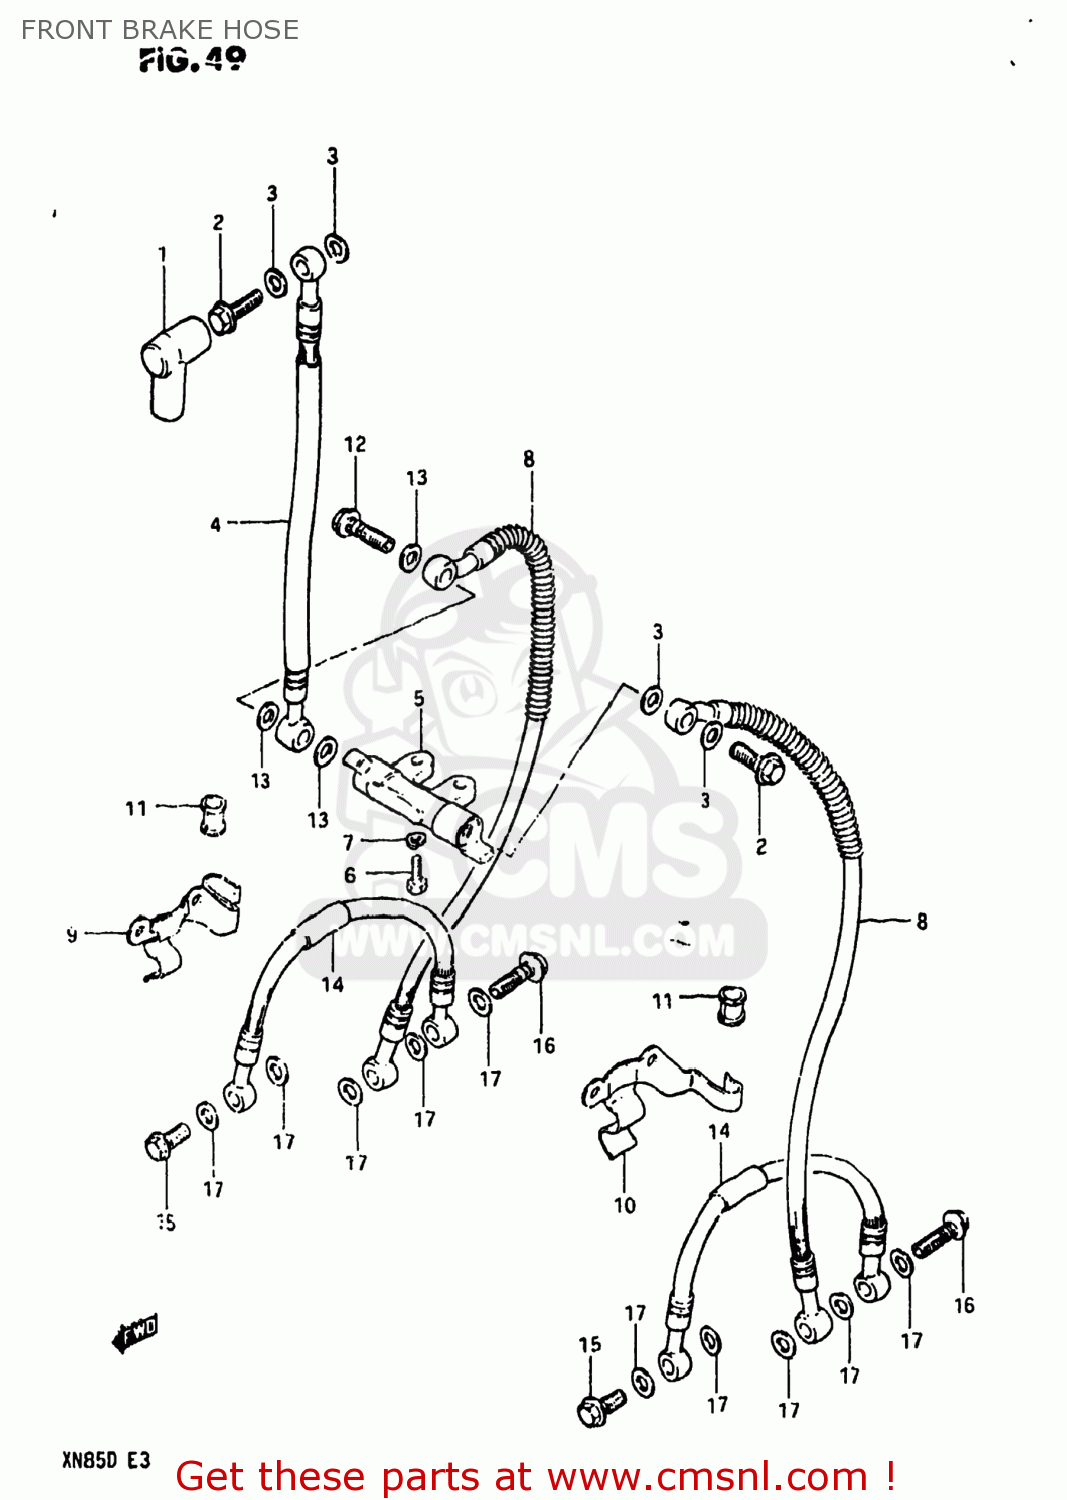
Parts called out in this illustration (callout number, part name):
1	BOOT
2	BOLT,UNION
3	WASHER
4	HOSE,BRAKE NO.1
5	JOINT,BRAKE HOSE
6	BOLT
7	LOCK WASHER
8	HOSE,FRONT BRAKE
9	CLAMP,FRONT BRAKE HOSE
10	CLAMP,FRONT BRAKE HOSE
11	BUSH,BRAKE HOSE GUIDE,NO.2
12	BOLT,UNION
13	WASHER
14	HOSE, UNTI NOSE
15	BOLT UNION
16	BOLT,UNION
17	WASHER
